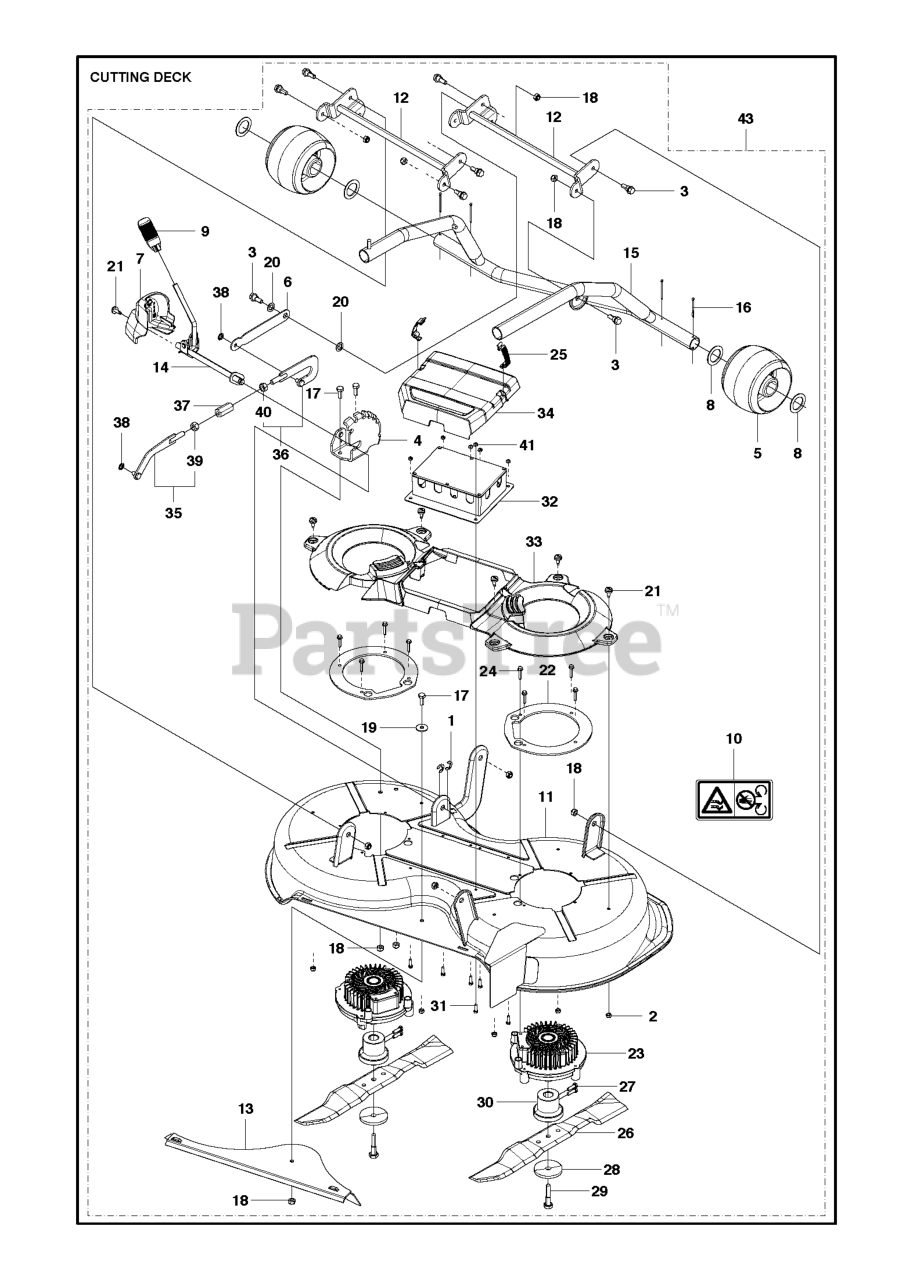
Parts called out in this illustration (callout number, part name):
1	RETAINING RING
2	LOCKNUT M6
16	COTTER PIN
18	LOCKNUT M8
25	BUCKLE ORANGE
28	WASHER
41	LOCKNUT M5
